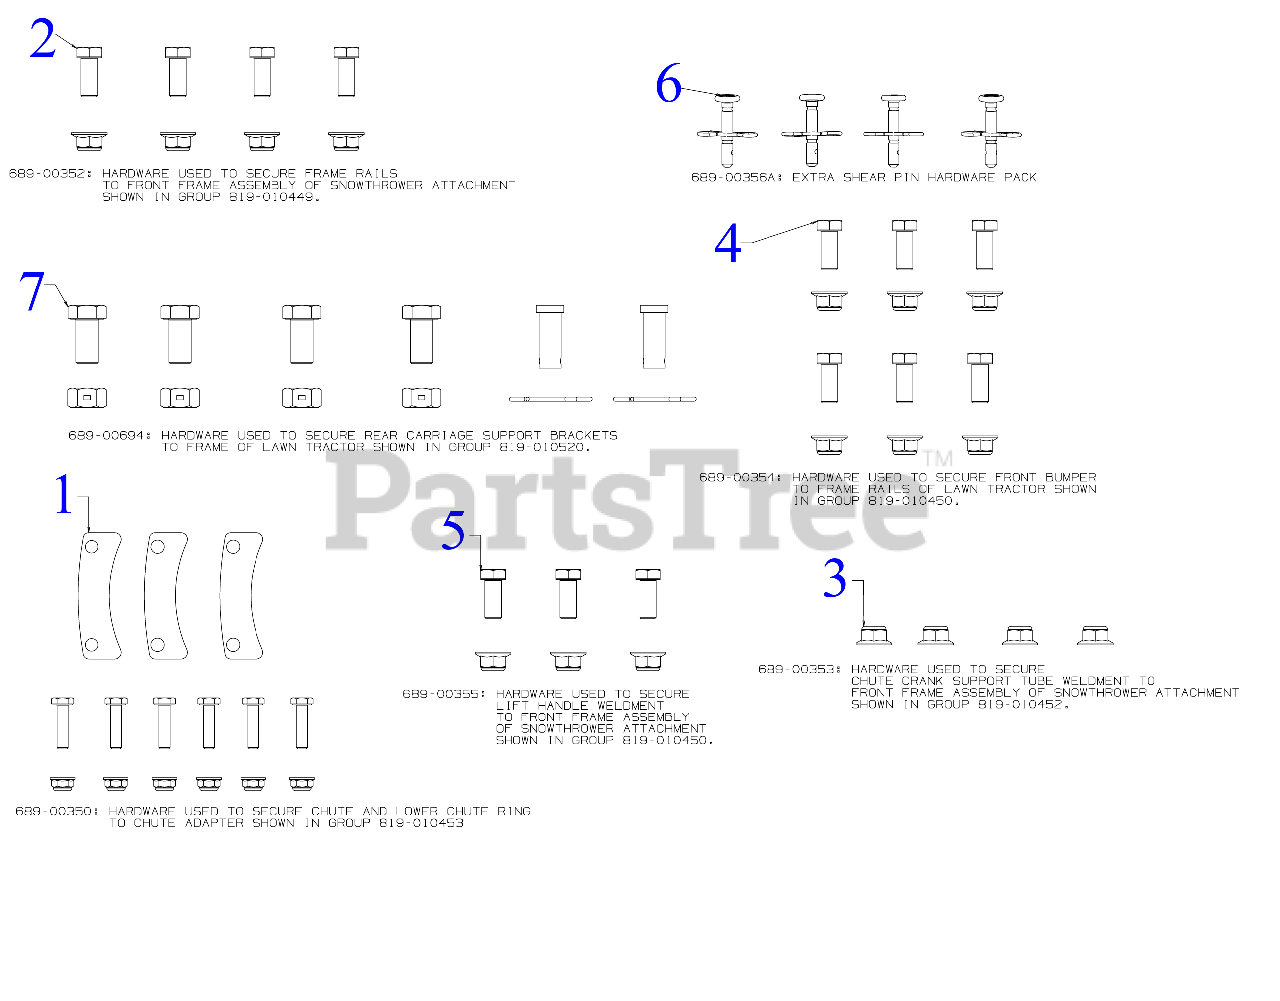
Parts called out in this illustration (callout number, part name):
1	HARDWARE PACK
1	SCREW 1/4-20 X1.00 GR5
1	FLANGE LOCK NUT
1	CHUTE FLANGE KEEPER
2	HARDWARE PACK
2	SCREW 3/8-16 x .880 GR5
3	HARDWARE PACK
4	HARDWARE PACK
4	SCREW 3/8-16 x .880 GR5
5	HARDWARE PACK
5	SCREW 3/8-16 x .880 GR5
6	HARDWARE PACK (SPARE SHEAR PINS)
6	BOW TIE COTTER PIN 1/4-5/16
6	SHEAR PIN (.25 x 1.50)
7	HARDWARE PACK
7	CLEVIS PIN .500 x 1.25
7	BOW TIE COTTER PIN
7	SCREW 1/2-13 x 1.0 GR5
7	HEX NUT CENTER
